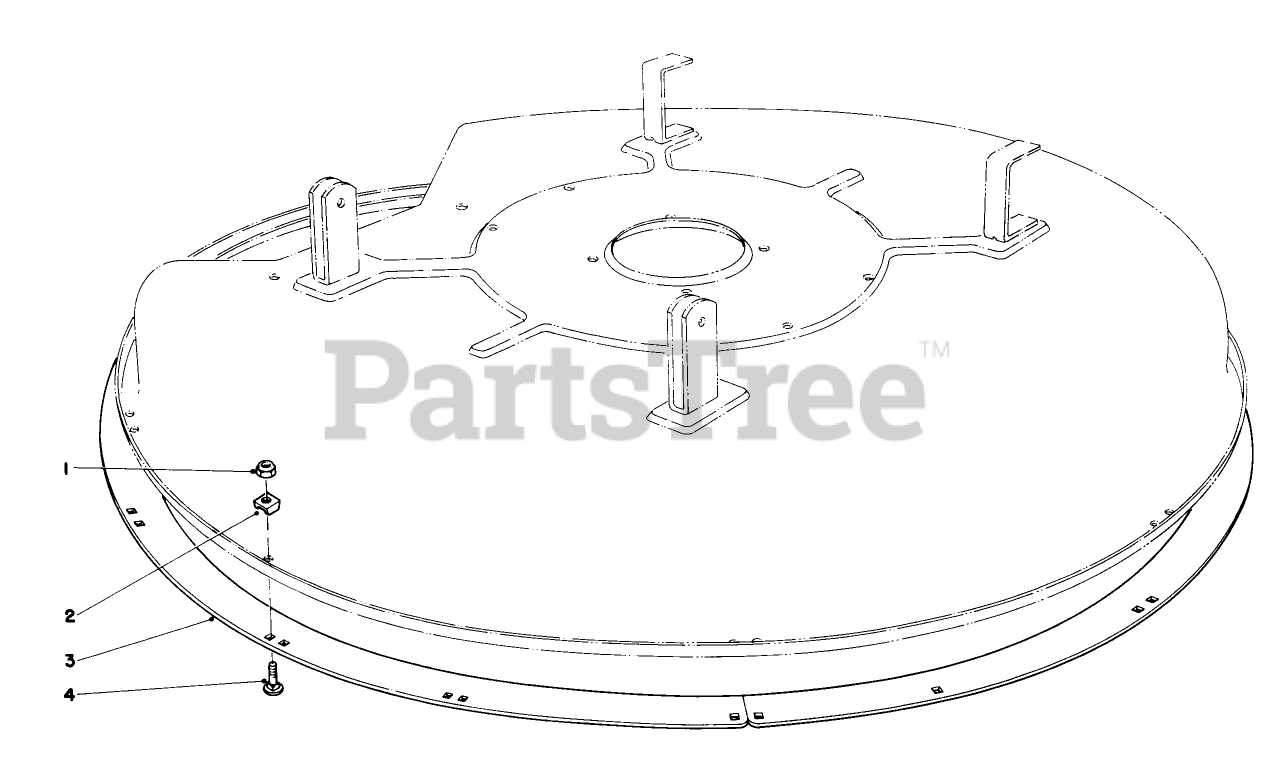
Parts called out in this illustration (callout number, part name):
1	NUT-LOCK, NI
3	DECK RING *B
4	BOLT-CARR
